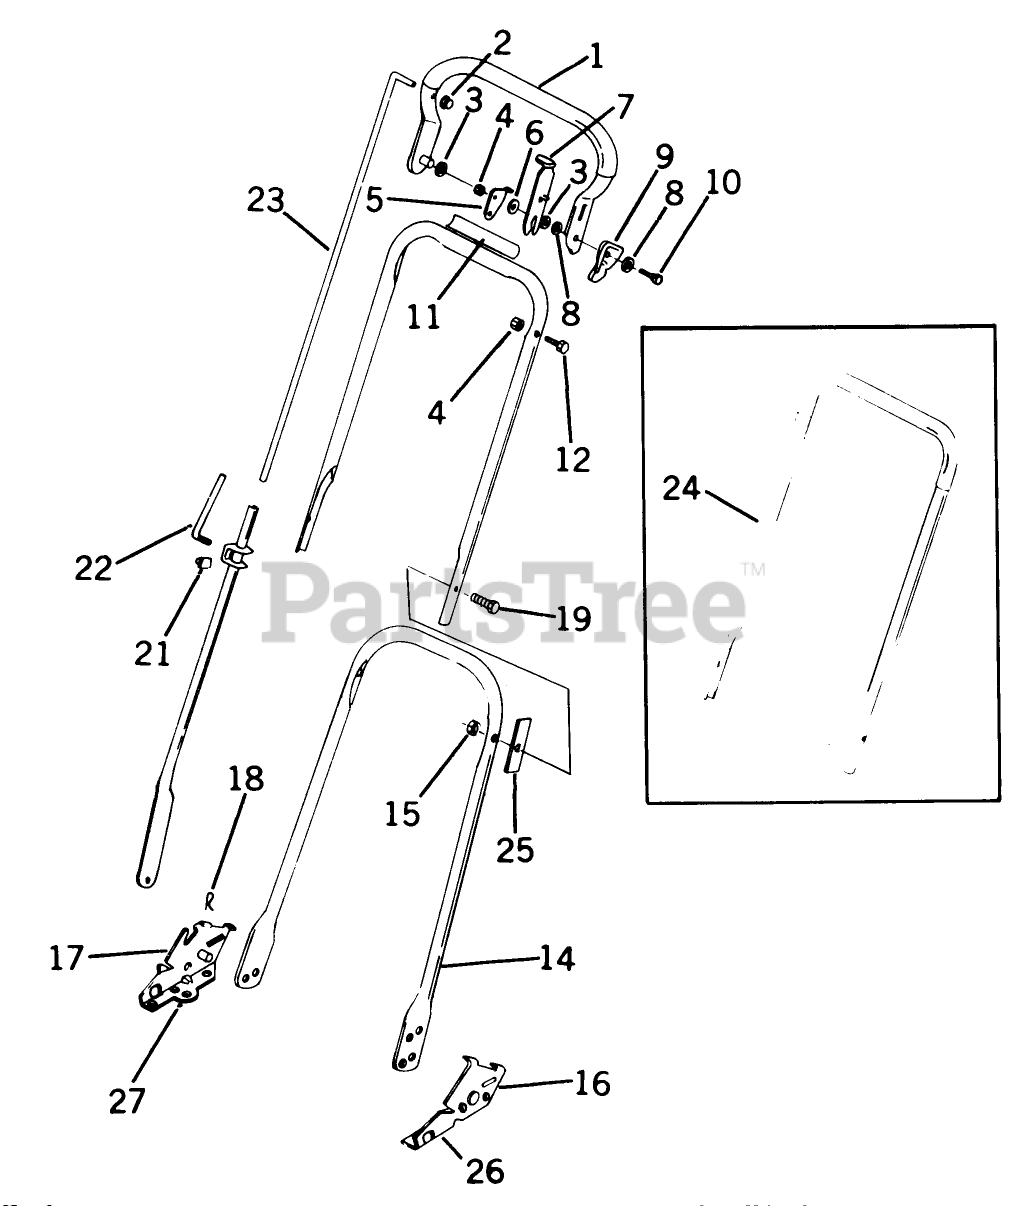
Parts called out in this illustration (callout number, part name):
3	WASHER M
4	LOCKNUT E
5	HANDLE STOP
6	WASHER
7	LEVER LOCKOUT
10	BOLT PIONEER
12	SCREW-HANDLE STOP
15	LOCKNUT E
17	HANDLE BRACKET
18	HAIR PIN
19	SCREW - USE 137-3042
23	ROD CONTROL
